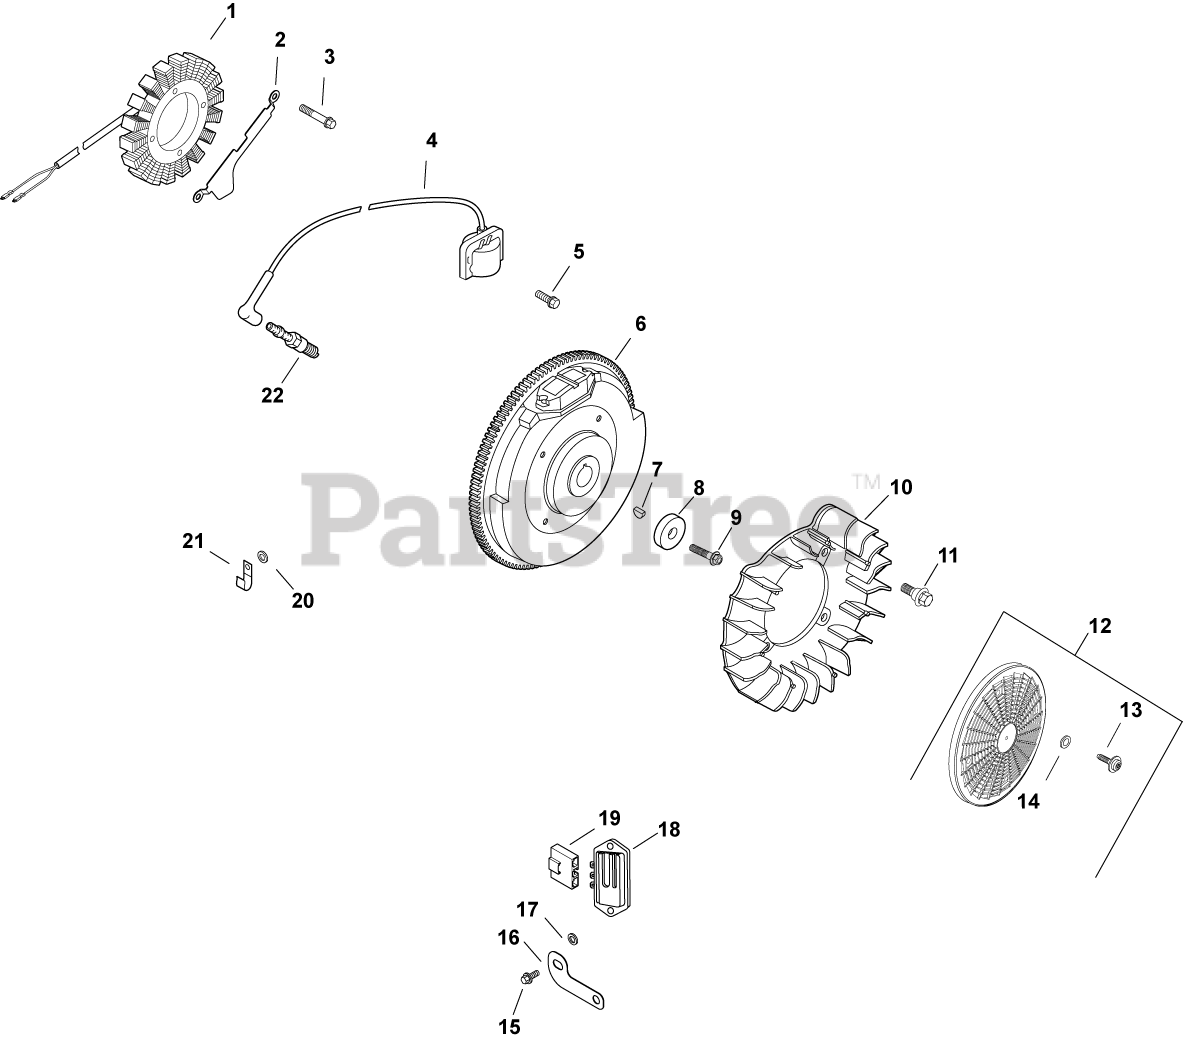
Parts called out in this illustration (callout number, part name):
1	KIT, 15 / 20 AMP STATOR
2	BRACKET, STATOR WIRE
3	SCREW, M5X0.8X25 - (#25086402S)
4	MODULE, IGNITION-USE 24 584 45-S
5	SCREW, FLG THD FRM M5X.8X20-(#25086399S)
7	KEY, 3/16" X 5/8"
8	WASHER, FLAT 13/32"
9	SCREW, FLG M10X1.5X45 - (#25086361S)
10	FAN (DOMED)-USE 24 157 17-S
11	BOLT, SHOULDER
12	KIT, GRASS SCREEN
13	SCREW, FLG SEMS M4X.7X25
14	WASHER, FLAT 3/16"
15	SCREW, PHL HD #11-16X7/8"
16	BRACKET, GROUND STRAP USE 24 518 12-S
17	WASHER, FLAT 7/32"
18	REG/RECT-15 AMP (KM)-USE 41 403 10-S
19	CONNECTOR, BODY (KM)-USE 25 155 41-S
20	WASHER, FLAT 1/4" (O.D. 1/2")
21	CLIP, CABLE
22	PLUG, SPARK (STD)
